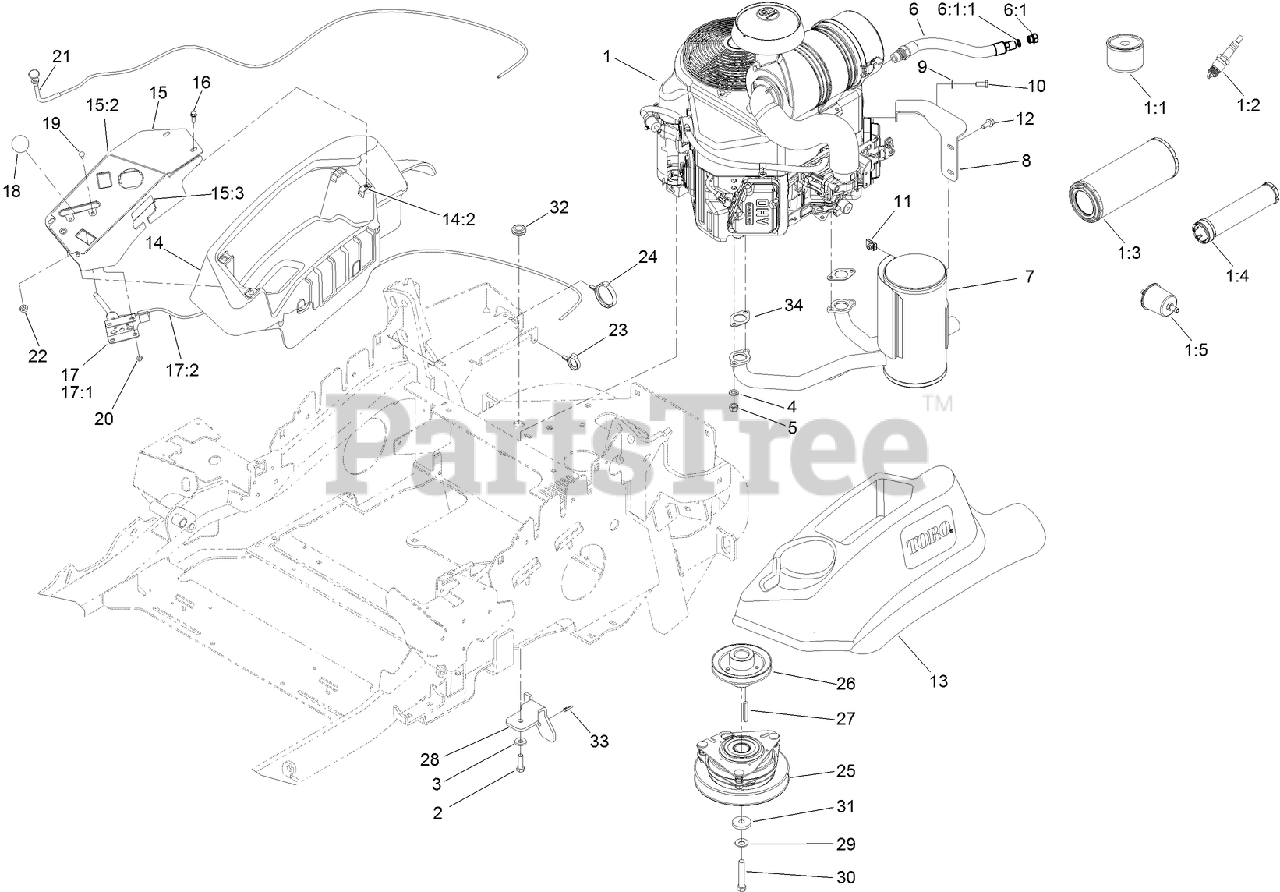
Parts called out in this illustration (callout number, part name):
1:1	FILTER-OIL
1:2	SPARK PLUG
1:3	ELEMENT-FILTER, AIR (OUTER)
1:4	ELEMENT-FILTER, AIR (INNER)
1:5	FILTER-FUEL
2	SCREW-HH
3	WASHER-BELLEVILLE
4	WASHER-LOCK
6	ENGINE OIL DRAIN HOSE ASM
6:1	PLUG-HH
6:1:1	O-RING
7	MUFFLER
8	BRACKET-MUFFLER
9	WASHER-SPRING
10	SCREW-HH
11	NUT-U
12	SCREW-HHF
13	CONSOLE-LH
14	RH CONSOLE ASM
15	CONTROL PANEL ASM
15:2	DECAL-PANEL, CONTROL
15:3	DECAL-FUSES
16	SCREW-HWH
17	THROTTLE CONTROL ASM
17:1	LEVER-THROTTLE
17:2	CABLE-THROTTLE
18	KNOB-BALL
19	BOLT-CARR
20	NUT-LOCK, NI
21	CONTROL-CHOKE
22	NUT-HJ
23	CLAMP-HOSE
24	CLAMP-HARNESS
25	CLUTCH
26	PULLEY-ENGINE
27	KEY-SQUARE
28	BRACKET-STOP, CLUTCH
29	WASHER-SPRING
30	SCREW-HH
31	WASHER
32	GROMMET
33	TIE-CABLE
34	GASKET-EXHAUST
